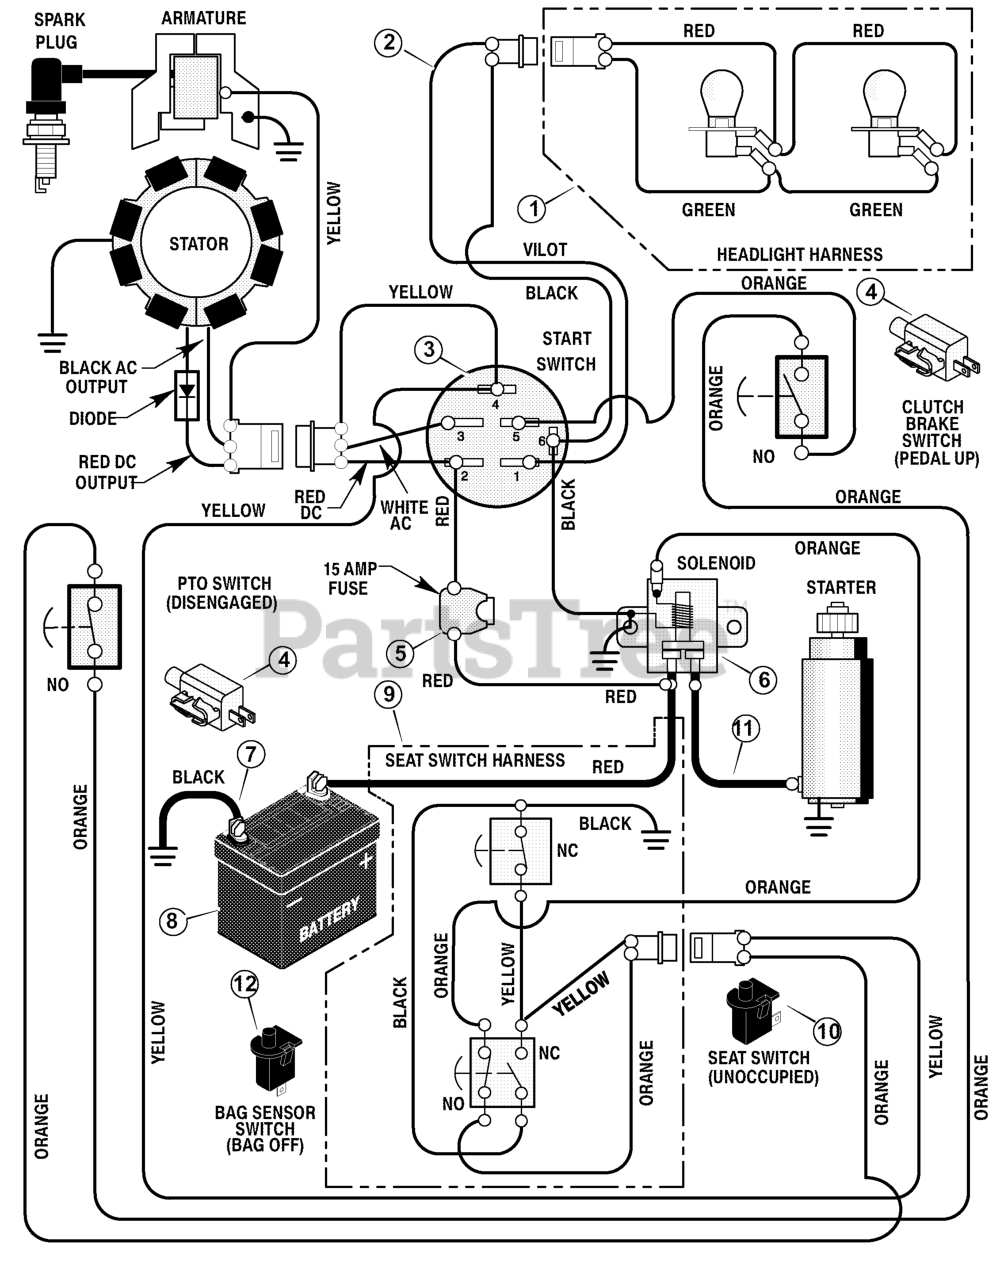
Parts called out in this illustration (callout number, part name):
1	Harness, Light Wire
2	Harness, Chassis Wire
3	Switch, Ignition
4	Switch, Limit
6	Solenoid
7	Cable, Battery Ground
8	Battery
9	Harness, Seat Switch Wire
10	Switch, Seat Sensor
12	Switch, Bag Sensor
